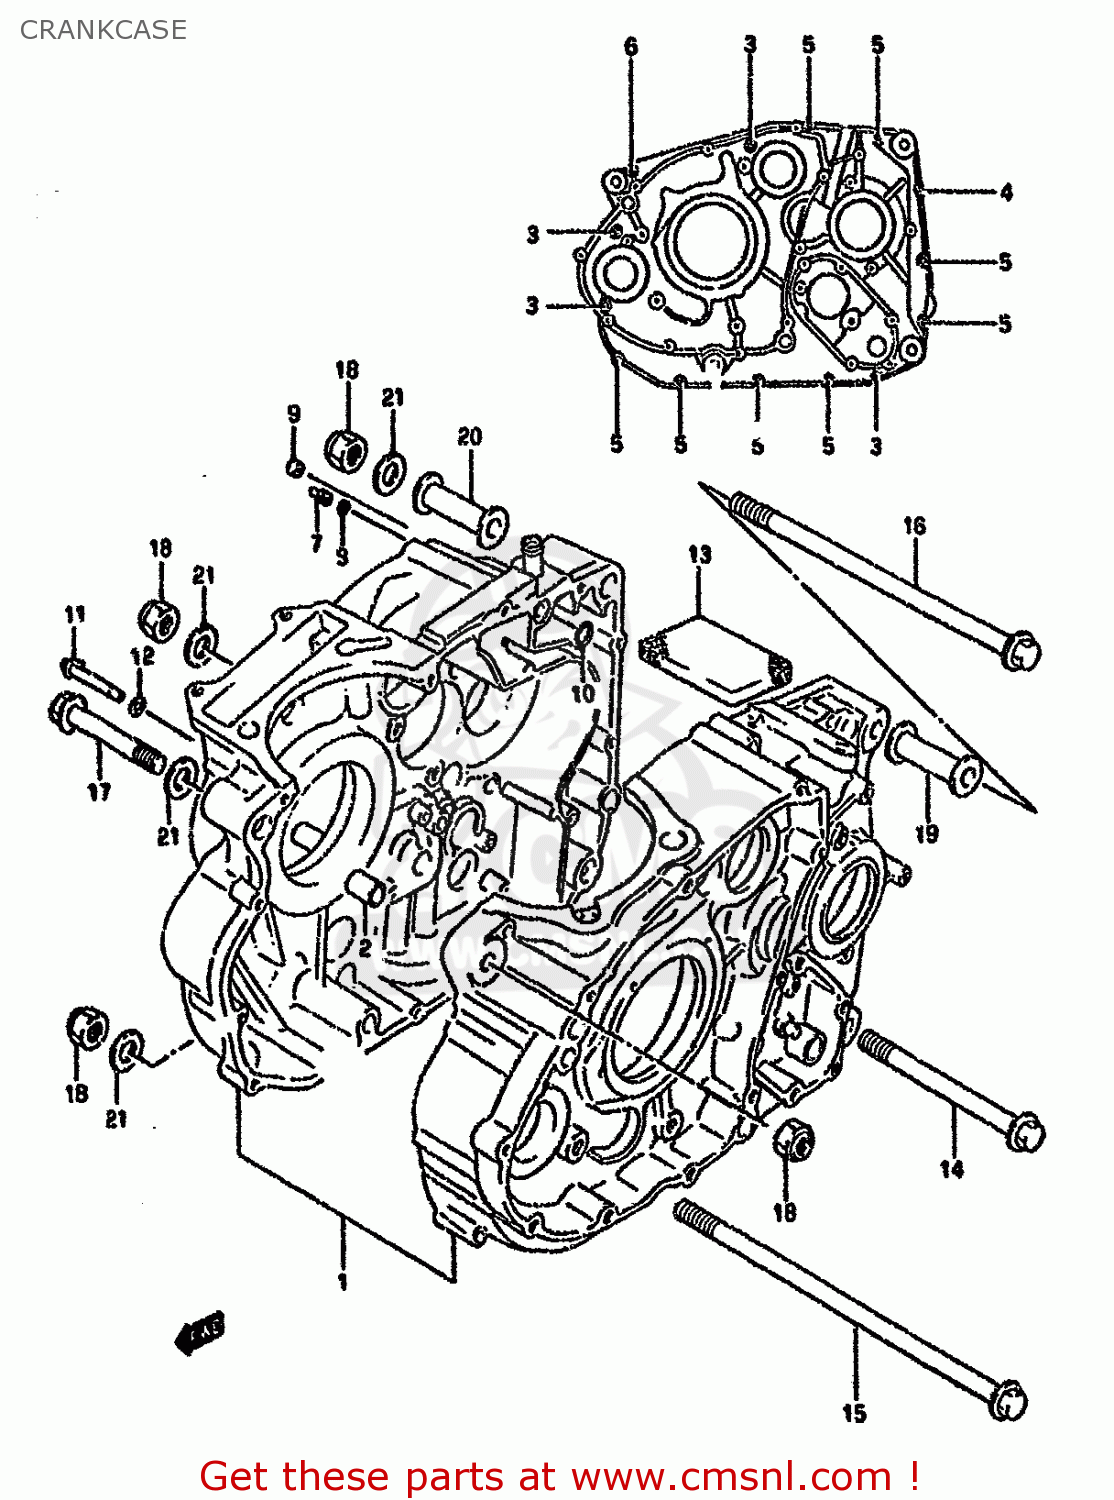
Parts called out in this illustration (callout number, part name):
1	CRANKCASE SET
2	PIN
3	BOLT
4	BOLT
5	BOLT
6	BOLT 6X30
7	JET(12)
8	O RING(D:1.2,ID:4)
9	JET,OIL GALLERY
10	O RING(D:1.9,ID:8.6)
11	PIPE,PISTON COOLING
12	O RING(D:1.9,ID:7.8)
13	SEPARATOR,OIL BREATHER
14	BOLT(10X130)
15	BOLT 10X230
16	BOLT(10X235)
17	BOLT(10X80)
18	NUT
19	SPACER,ENG MTG(L:55)
20	SPACER,ENGINE MOUNT(L:65)
21	WASHER
